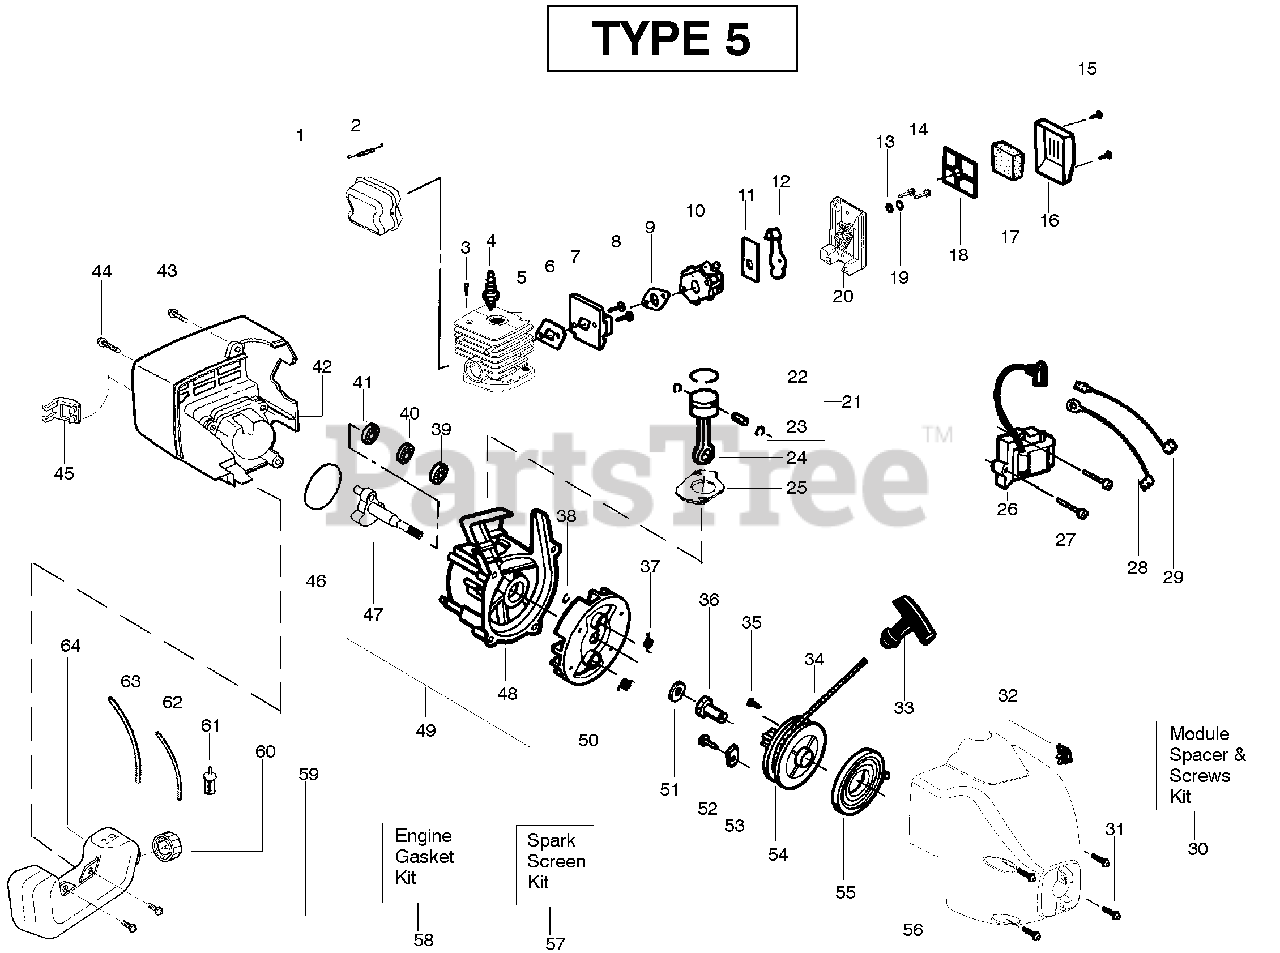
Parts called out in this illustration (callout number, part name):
1	Kit - Muffler
2	Muffler Spring
3	Screw-Cylinder
4	Spark Plug (RCJ 6Y)
5	Kit - Cylinder
6	Gasket-Cyl/Carb.(kit)
7	Adaptor-carb.
9	Gasket-Carb.(kit)
10	Kit-Carb. (WT-631)
11	Plate-Choke Mounting
12	Lever-Choke
16	Cover-Air Box
17	Foam-Air Filter
18	Plate-Air Filter Support
19	Spacer-Choke
21	Kit - Piston
22	Piston Ring
23	Retainer-Piston Pin
24	Assy-Connecting Rod
25	Gasket-Cylinder(kit)
26	Ignition Module
28	Assy-Ground Wire
29	Assy-Leadwire
30	Kit-Module Spacer & Screws
31	Screw
32	Kit-Switch
33	Handle-Starter
34	Kit - Rope
36	Coupling-Drive
37	Spring-Starter Dog
38	Retain. Ring-C'shaft
39	Bearing-Outer
40	Kit-Seal C'case
41	Bearing-Inner
44	Screw
45	Guard-Muffler
46	O-Ring-C'case(kit)
47	Assy-Crankshaft
48	Assy-Crankcase
49	Assy-C'case & C'shaft
50	Assy-Flywheel
51	Washer-Flat
53	Retainer-Can
54	Kit-Starter Pulley
55	Spring-Starter
56	Assy-Fan Housing
57	Kit-Spark Screen
58	Kit-Engine Gasket
59	Retainer-Tank
60	Assy-Fuel Cap
61	Assy-Fuel Pickup
62	Kit-Fuel Line
63	Kit-Fuel Line
64	Assy-Fuel Tank
